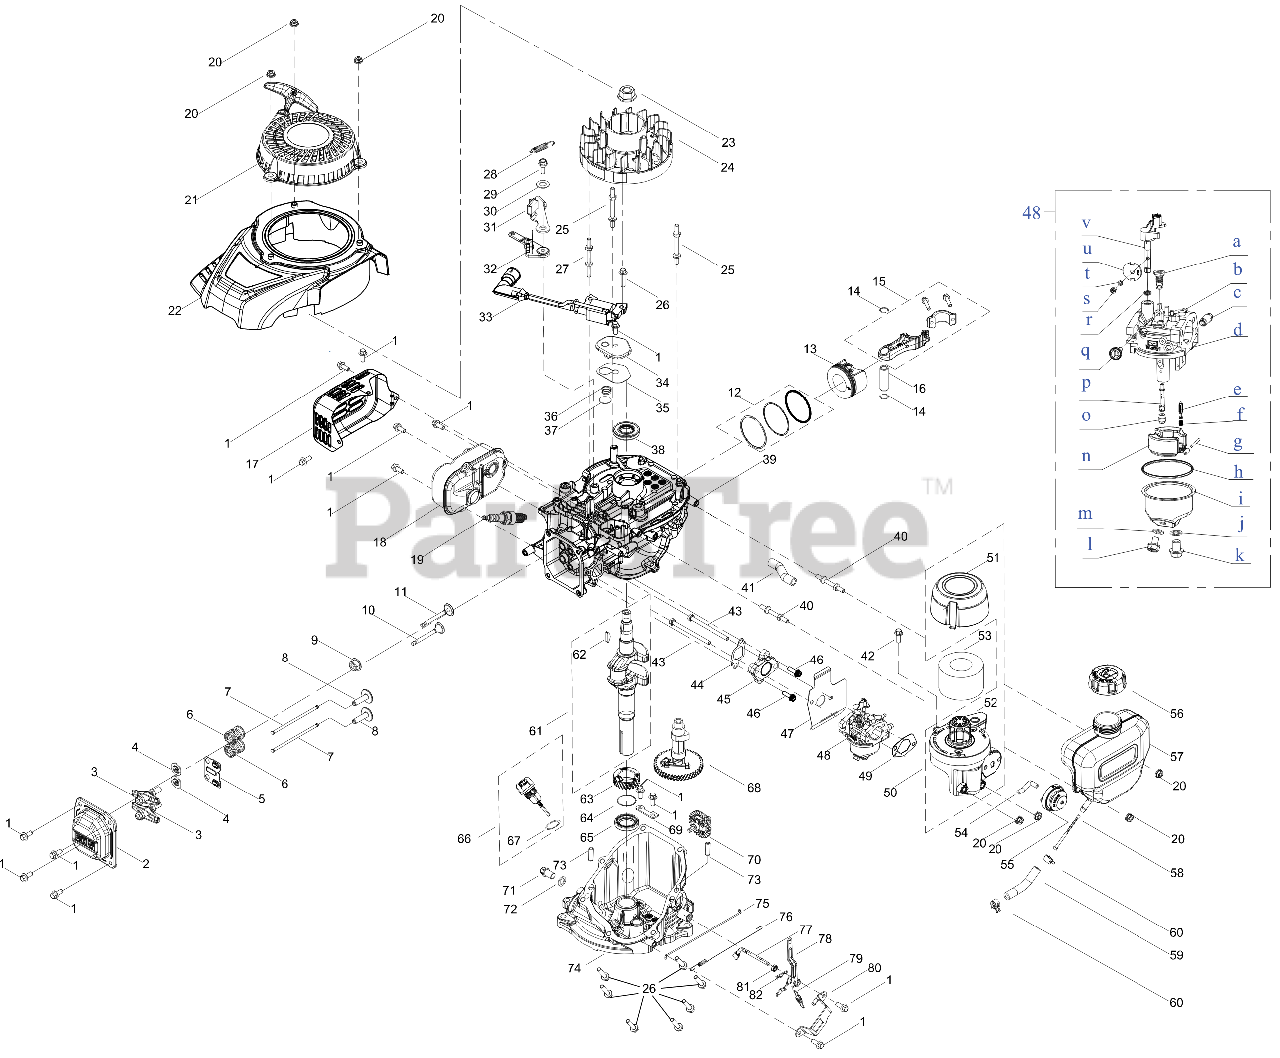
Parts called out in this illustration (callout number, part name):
1	BOLT M6-1 x 14 GR8.8
2	VALVE COVER
3	ROCKER ARM ASSEMBLY
4	VALVE SPRING RETAINER
5	PUSH ROD GUIDE
6	VALVE SPRING
7	PUSH ROD
8	TAPPET (LIFTER)
9	INTAKE VALVE SEAL
10	EXHAUST VALVE
11	INTAKE VALVE
12	PISTON RING SET
13	PISTON
14	SNAP RING-PISTON PIN
15	CONNECTING ROD
16	PISTON PIN
17	MUFFLER GUARD
18	MUFFLER
19	SPARK PLUG
20	HEX NUT
21	STARTER RECOIL ASSEMBLY
22	ENGINE SHROUD
23	FLYWHEEL NUT
24	FLYWHEEL
25	STUD M6 x 75
26	BOLT M6-1 x 25 GR8.8
27	STUD M6 x 73
28	ENGINE BRAKE SPRING
29	ENGINE BRAKE PIN M6-1.0 MM
30	FLAT WASHER 10x20x1.0 MM
31	ENGINE BRAKE ARM
32	ENGINE BRAKE LOWER BRACKET
33	IGNITION COIL
34	BREATHER COVER PLATE
35	BREATHER GASKET
36	BREATHER VALVE SPRING
37	BREATHER VALVE
38	UPPER CRANKSHAFT SEAL
39	CRANKCASE
40	FUEL TANK MOUNTING STUD M6X59.5
41	BREATHER HOSE
42	SCREW M6-1 x 16 CL8.8
43	BOLT M6X80
44	CARBURETOR INSULATION GASKET
45	CARBURETOR INSULATOR
46	BOLT M6X20
47	CARBURETOR GASKET
48	CARBURETOR
49	AIR FILTER BASE GASKET
50	AIR FILTER ASSEMBLY
51	AIR FILTER COVER
52	AIR FILTER BASE
53	AIR FILTER - FOAM
53	Genuine Factory Parts AIR FILTER FOAM
54	PRIMER HOSE
55	VENTED PRIMER ASSEMBLY
56	FUEL CAP ASSEMBLY
57	FUEL TANK
58	FUEL FILTER
58	Genuine Factory Parts FUEL FILTER
59	FUEL HOSE
60	HOSE CLAMP
61	CRANKSHAFT
62	FLYWHEEL KEY
63	CRANKSHAFT TIMING GEAR
64	THRUST WASHER
65	LOWER CRANKSHAFT SEAL
66	DIPSTICK ASSEMBLY
67	DIPSTICK SEAL
68	CAMSHAFT
69	GOVERNOR GEAR MOUNTING PLATE
70	GOVERNOR GEAR/SHAFT ASSEMBLY
71	OIL DRAIN PLUG
72	WASHER
73	DOWEL PIN 7X20
74	CRANKCASE COVER
75	THROTTLE LINKAGE
76	THROTTLE LINKAGE SPRING
77	GOVERNOR ARM SHAFT
78	GOVERNOR ARM ASSEMBLY
79	GOVERNOR SPRING
80	COMPONENT BRACKET
81	GOVERNOR SEAL
82	COTTER PIN
